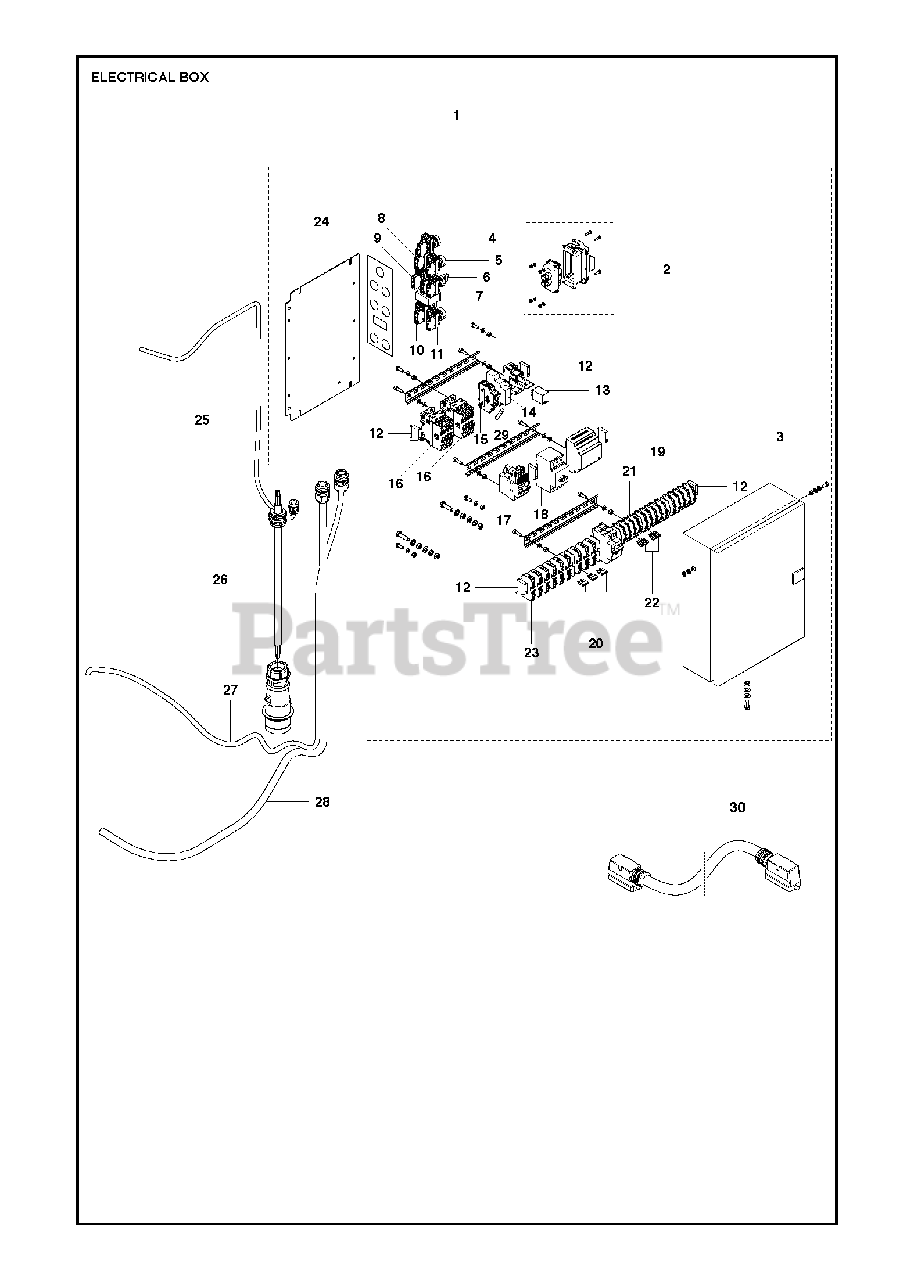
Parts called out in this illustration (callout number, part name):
24	PLATE-01 EU/AUS / -02 UL/CSA
25	CABLE ASSY-01 EU / -02 AUS / -03 UL/CSA
26	CABLE ASSY-01 EU/AUS / -02 UL/CSA
27	CABLE ASSY-01 EU/AUS / -02 UL/CSA
